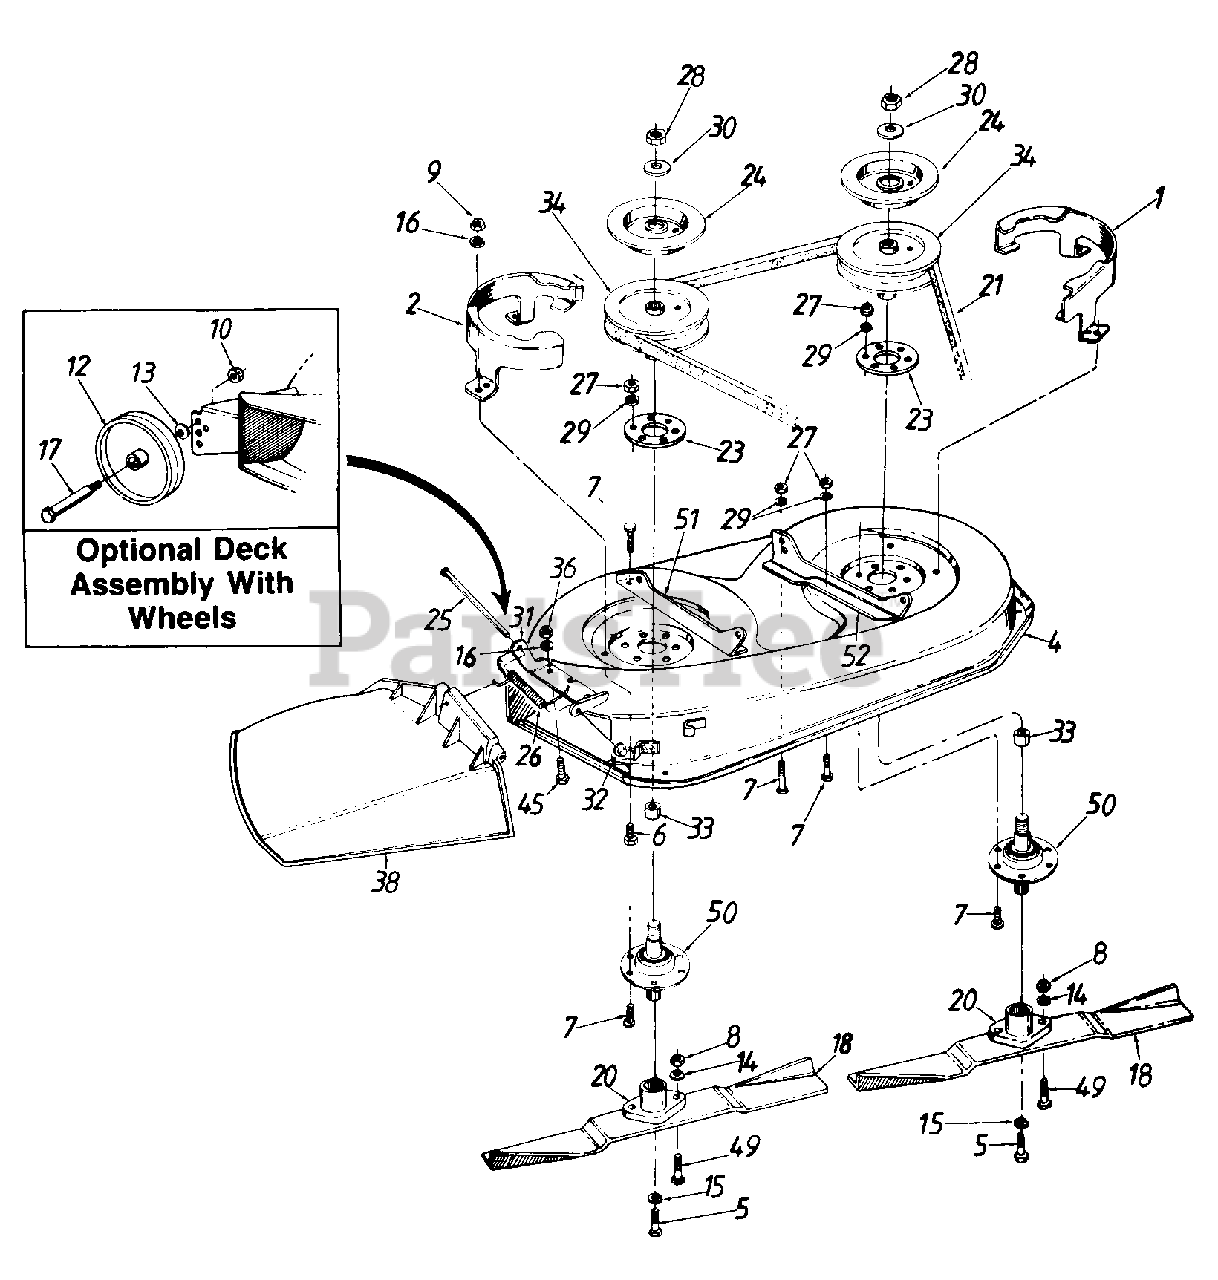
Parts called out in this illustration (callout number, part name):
5	Hex Bolt 3/8-24 x 1.0" Lg.
6	Hex Bolt 1/4-28 x .62" Lg.
7	Hex Bolt 5/16-24 x .75" Lg.
8	Hex Nut 5/16-24 Thd.
9	Hex Nut 1/4-28 Thd.
10	Hex L-Nut 3/8-16 Thd
12	Deck Wheel
13	Bell-Wash. .380" I.D. x .88
14	L-Wash. 5/16" I.D.
15	L-Wash. 3/8" I.D. H.D.
16	Bell-Wash. .265" I.D. x .75
17	Shld. Bolt .498" Dia. x 1.53
18	High-Lift Blade
20	Blade Adapter
21	V-Belt
24	Brake Disc
25	Hinge Pin
26	Torsion Spring
27	Hex Nut 5/16-24 Thd.
28	Hex Jam Nut 5/8-18 Thd.
29	L-Wash. 5/16" I.D.
30	L-Wash. 5/8" I.D.
31	Hinge Mtg. Brkt.
32	Push Nut
33	Spacer
34	5" Dia. Pulley
36	Hex Nut 1/4-20 Thd.
38	Chute Ass'y. Comp.
45	Truss-Mach. Scr. 1/4-20 x .75 Lg.
49	Hex Bolt 5/16-24 x 1.0" Lg.
50	Blade Spindle Complete
51	Deck Bracket-R.H.
52	Deck Bracket-L.H.
